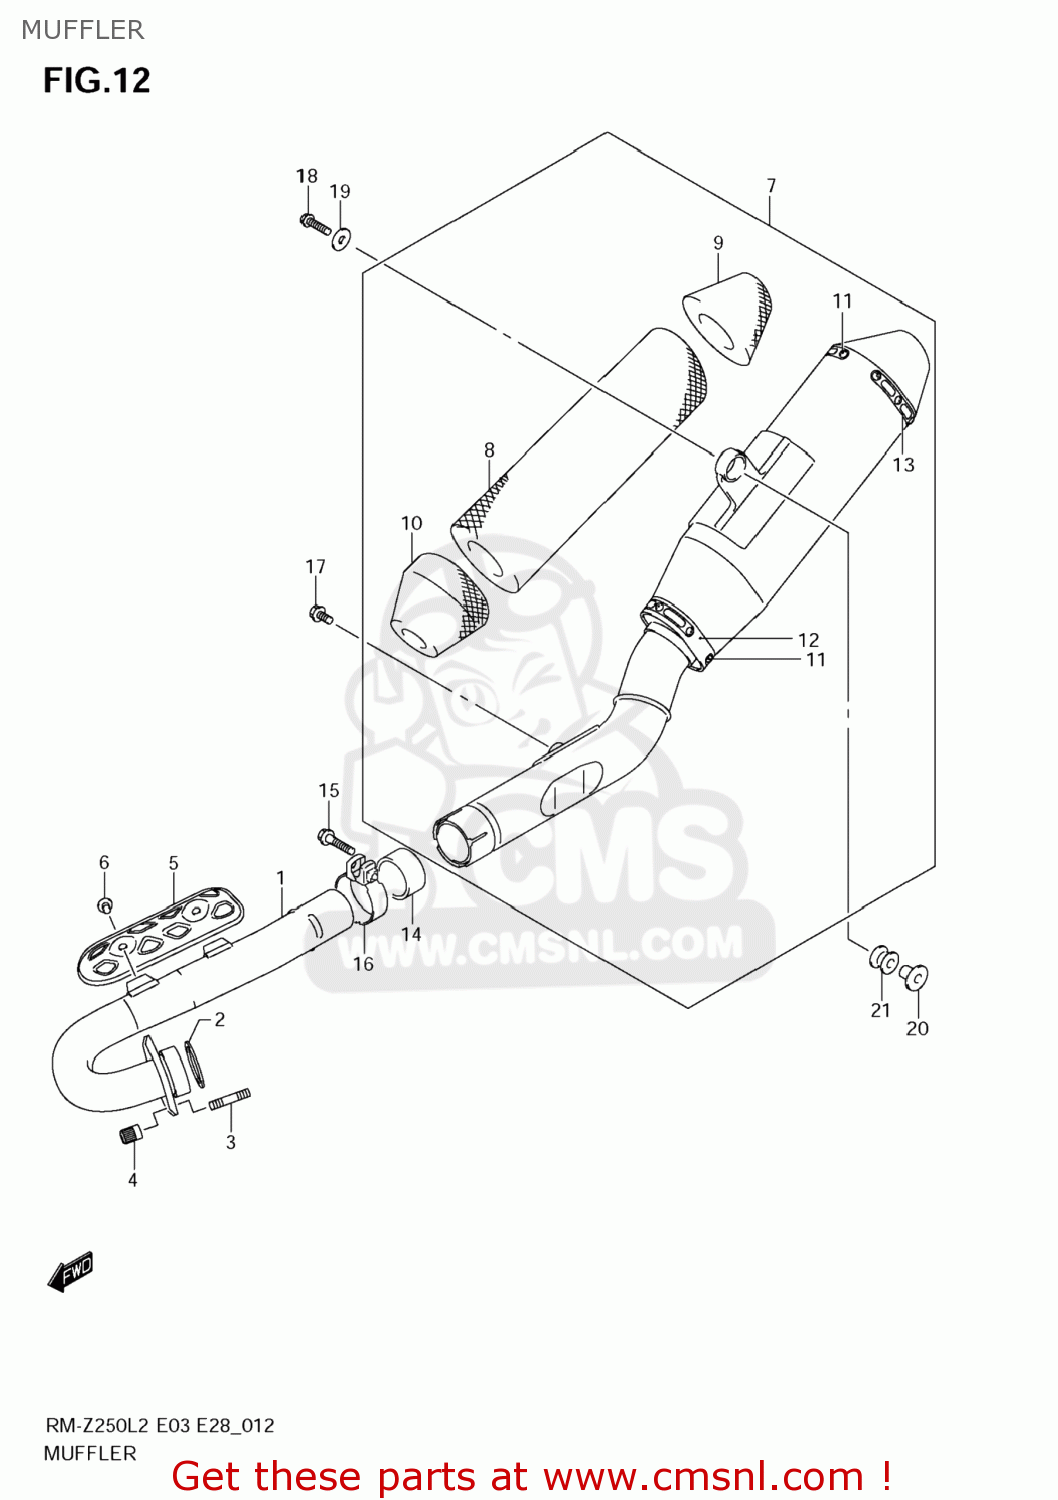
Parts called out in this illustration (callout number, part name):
1	PIPE,EXHAUST
2	GASKET,EXHAUST PIPE (NAS)
3	BOLT,STUD
4	NUT
5	COVER,EXHAUST PIPE
6	BOLT(6X8)
7	BODY,MUFFLER
8	SILENCER,MUFFLER
9	GLASS WOOL,MUF TAIL
10	GLASS WOOL,MUF FR
11	RIVET,MUFFLER
12	BAND,MUFFLER
13	BAND,MUFFLER
14	CONNECTOR,MUFFLER
15	BOLT
16	CLAMP,CONNECTOR
17	BOLT(8X20)
18	BOLT(8X35)
19	WASHER(8.5X26X1.6)
20	SPACER(8.6X12X18.5)
21	CUSHION
